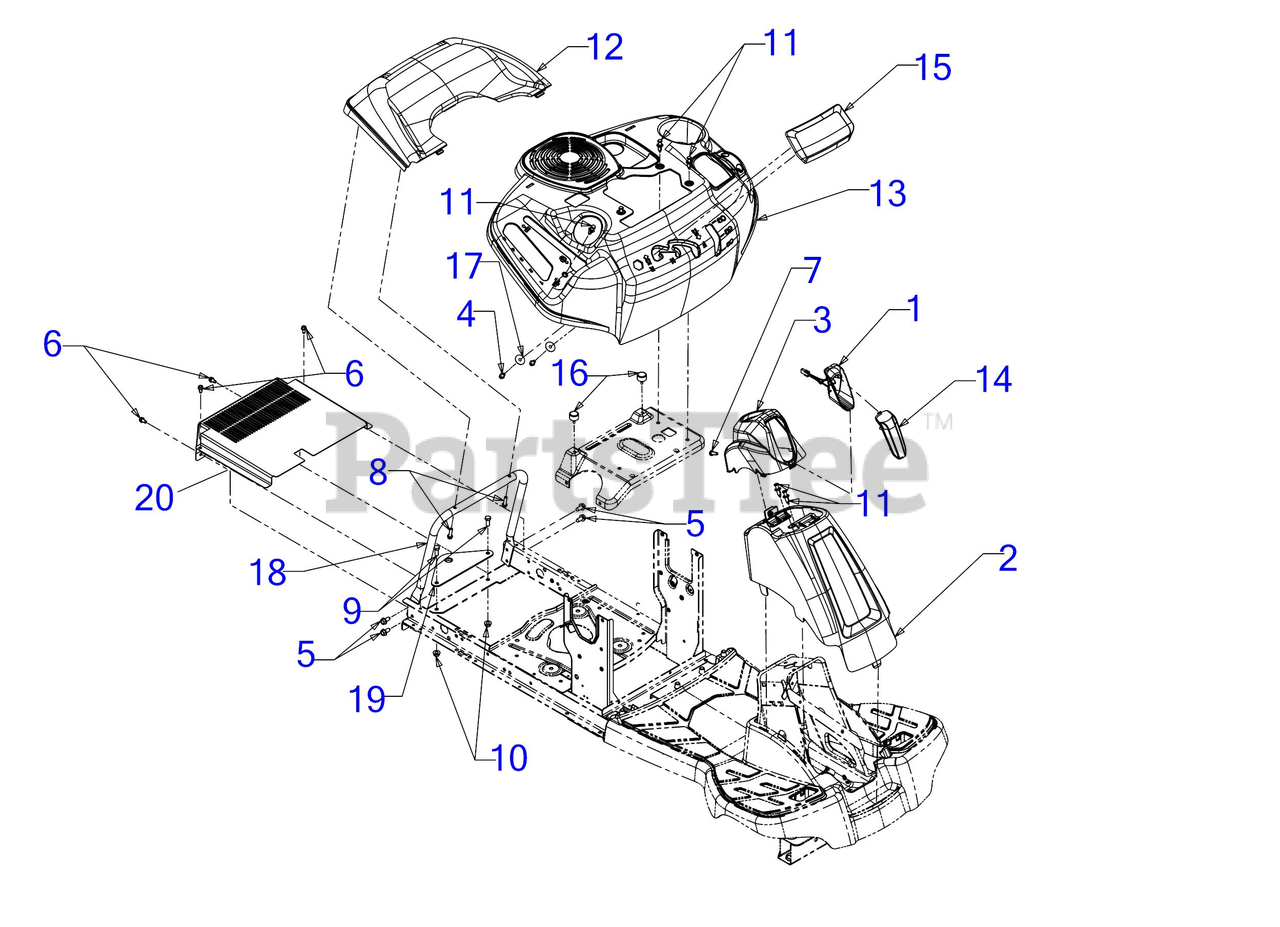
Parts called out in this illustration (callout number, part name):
1	HEADLIGHT HARNESS ASSEMBLY
2	COLUMN COVER ASSEMBLY (CUB)
3	COLUMN CAP (CUB YELLOW)
4	HEX SCREW 1/4-15 x .50
5	SCREW 5/16-18 x .750
6	SCREW 1/4-20 X.500
7	SCREW 1/4-20X.75
8	SCREW 1/4-15 x 1.00
9	SCREW 5/16-18 x .75 GR5
10	FLANGE LOCK NUT 5/16-18
11	PLASTIC RIVET
14	LED HEADLIGHT LENS
15	FENDER COVER
16	BUMPER .62 DIA x .50
17	FLAT WASHER
19	HITCH PLATE
20	HYDRO COVER HEAT SHIELD (B&S)
